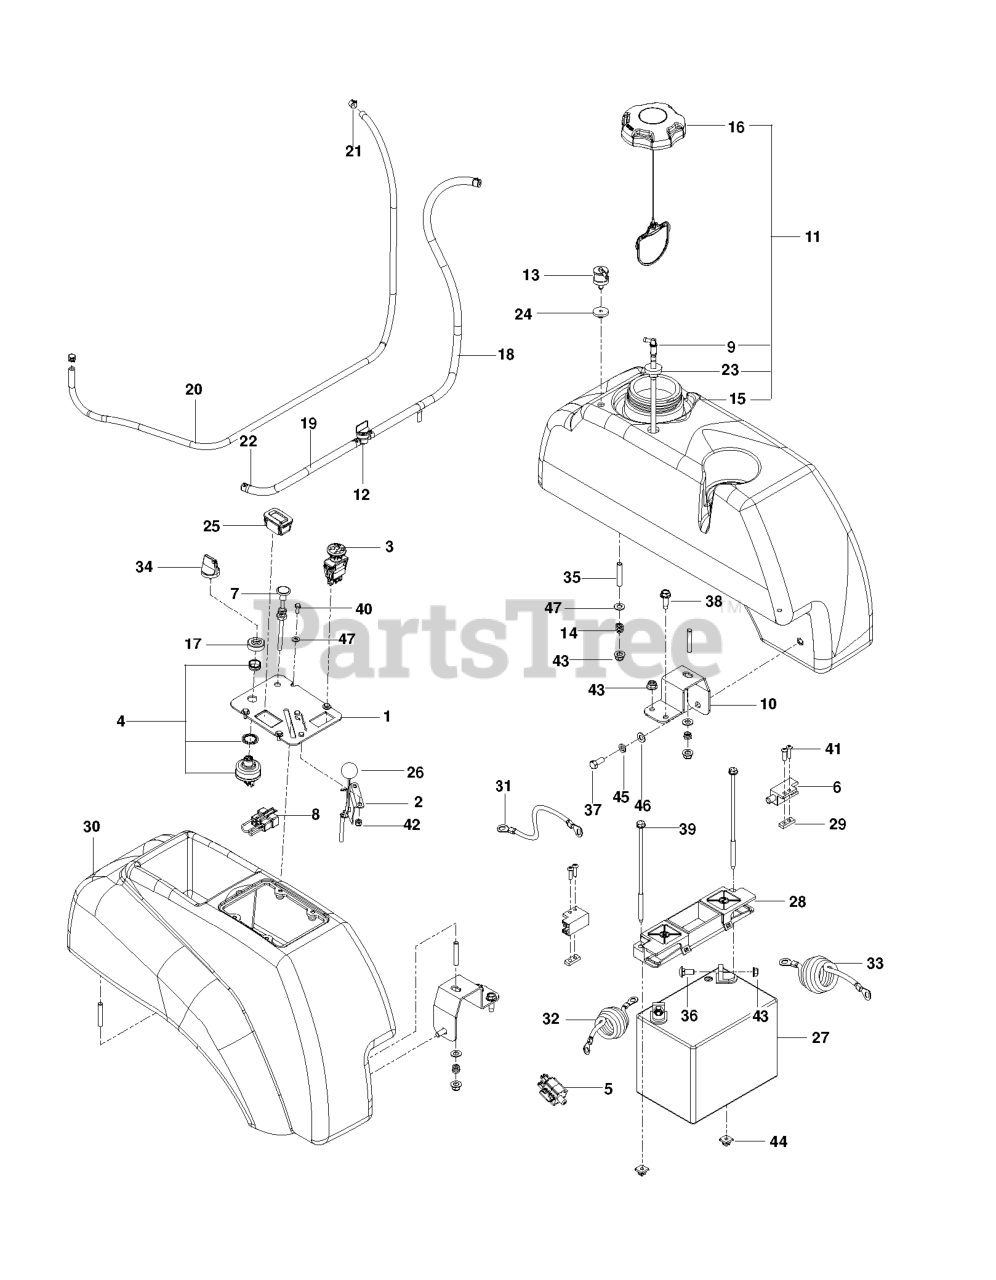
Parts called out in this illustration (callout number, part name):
1	PLATE.CONSOLE.BLACK
2	THROTTLE CABLE
3	SWITCH, PTO 10 AMP
4	SWITCH, IGNITION, INDAK
5	SWITCH, BRAKE 3P
6	SWITCH INTERLOCKT
7	CABLE, CHOKE
8	PLUG, TIMER
9	FITTING, FUEL
10	SUPPORT, TANK, BLK
11	TANK FUEL LT ASM MZ GRAY
12	FUEL VALVE
13	VALVE.FUEL.CHECK
15	TANK, FUEL, LT-EPA
16	CAP, FUEL
17	CAP IGNITION NUT
18	HOSE, FUEL .25 ID X 26"
19	GAS LINE 10"
20	HOSE, VAPOR 3/16 X 48"
21	CLAMP, HOSE
22	HOSE CLAMP
23	RUBBER GROMMET
24	GROMMET, CHECK VALVE
25	RP.GUAGE.SRVCMNDR.HRMTR.
26	KNOB.ROUND.BALL.BLACK
27	BATTERY, 12 V 330 AMP
28	BATTERY HOLD DOWN
29	TAPPED PLATE
30	FENDER CONSOLE
31	POST.CABLE LONG
32	CABLE POSITIVE
33	NEG. CABLE, 28"
34	KEY, IGNITION
35	STUD, 5/16C
36	BOLT 5/16C X 3/4" CARRIAGE
37	HCS 5/16C X 3/4
38	RP BLT 5/16-18 X 1 THRD FORM D
39	BOLT - 1/4-20 X 7.5
40	HCS #10-24 X 1/2
41	SCR #10-24 X .75 SKT HD BLK
42	NUT 10-24 NYLOC
43	5/16-18 NYLOC FLANGE NUT
44	PUSH NUT-NYLON
45	WASHER.LOCK.HVY.HLCL.SPR.5/16
46	FLAT WASHER 5/16 SAE
47	WASHER #10
